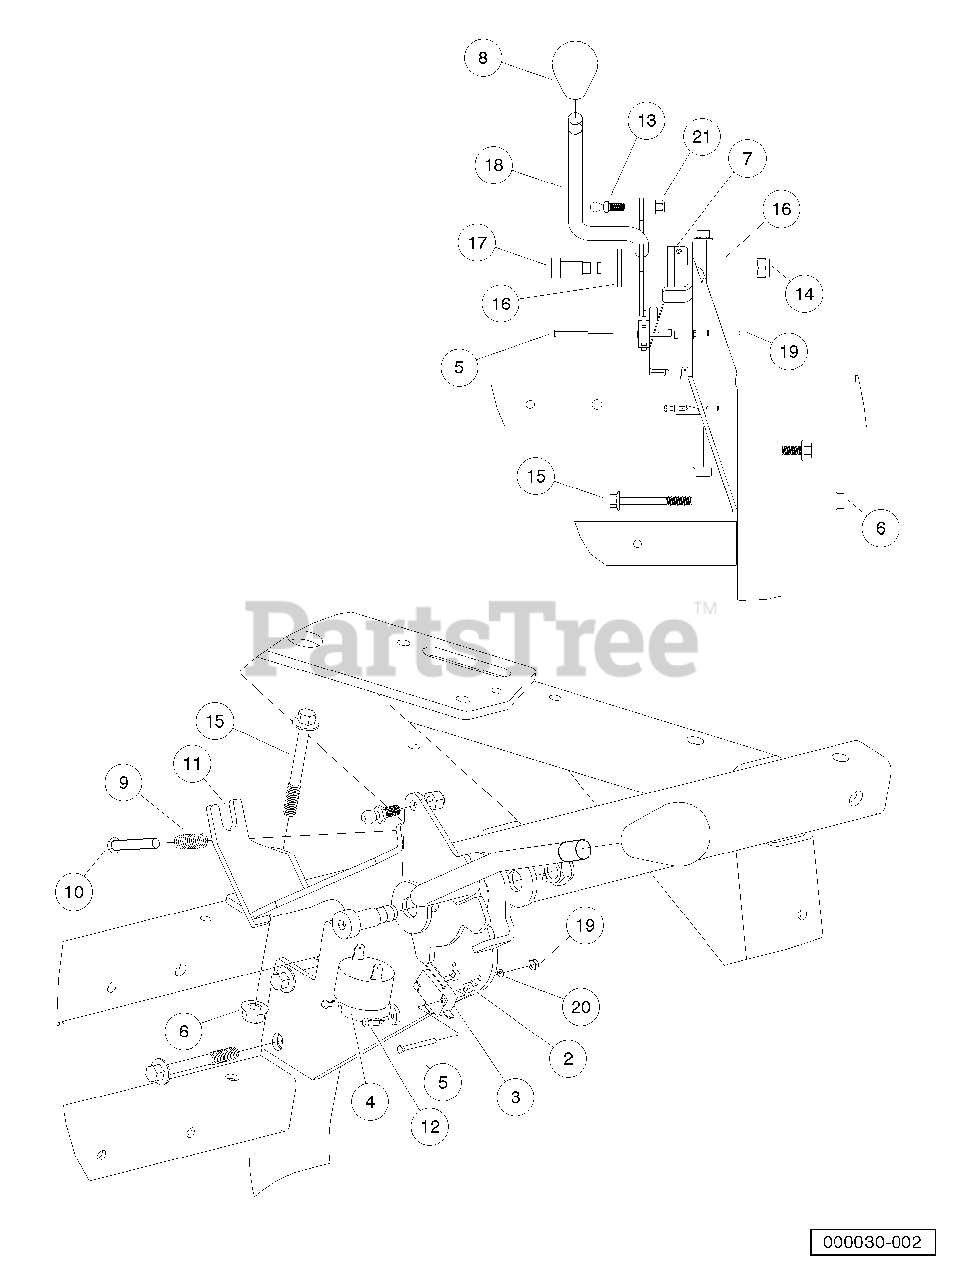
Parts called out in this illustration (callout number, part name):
1	Asm, FNR
2	Washer, #4 Nylon Flat
3	Switch, Limit
4	Buzzer, Reverse
5	Screw, #4-40 X 1.125 Hx Hd Mch
6	Nut,m8,all Metal Lock
7	Bushing, Fnr
9	Spring, Stop, Pedal
10	Bolt, Stop, Pedal
11	Weldment, FNR Shifter Bracket
12	Rivet, Micro Tuflok
13	Stud, Ball, .346 Dia
14	Locknut, M10x1.5 Nylon Insert
15	Bolt Flanged Head, M8 X 1.25 X 65
16	Washer, M12 Hard Regular
17	Shoulder Bolt,m12 X 20 M10 Thd
18	Weldment, FNR Shifter
19	Nut, #4-40 Hex Machine
20	Lockwasher, #4 Helical Split
21	Locknut, 1/4-28 Nylon Insert
